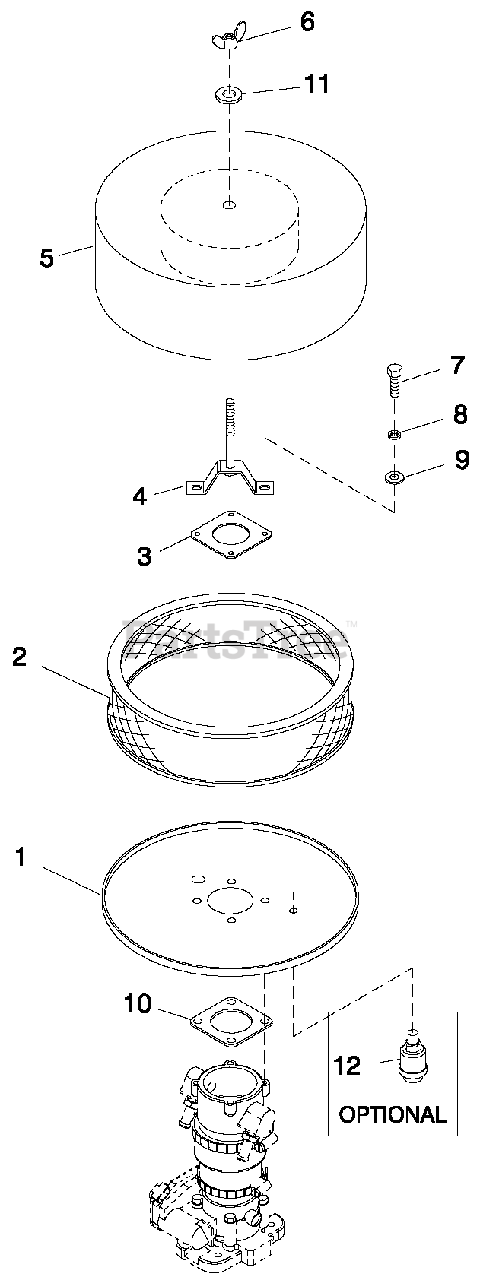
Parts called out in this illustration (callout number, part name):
1	AIR CLNR BTM PLT W/CPLR 8.1L
2	ELEMENT AIR FILTER
3	TOP PLATE VENTURI
4	HOLD DOWN AIR CLEANER PLATED
5	PLATE AIR CLEAN TOP 5.4L/6.8L
6	NUT WING 1/4-20 NYLK
7	SCREW HHC M6-1.0X 16 G8.8
8	WASHER LOCK M6-1/4
9	WASHER FLAT M6
10	GASKET MIXER BODY
11	WASHER FLAT 1/4-M6 ZINC
12	INDICATOR FILTER MINDER
